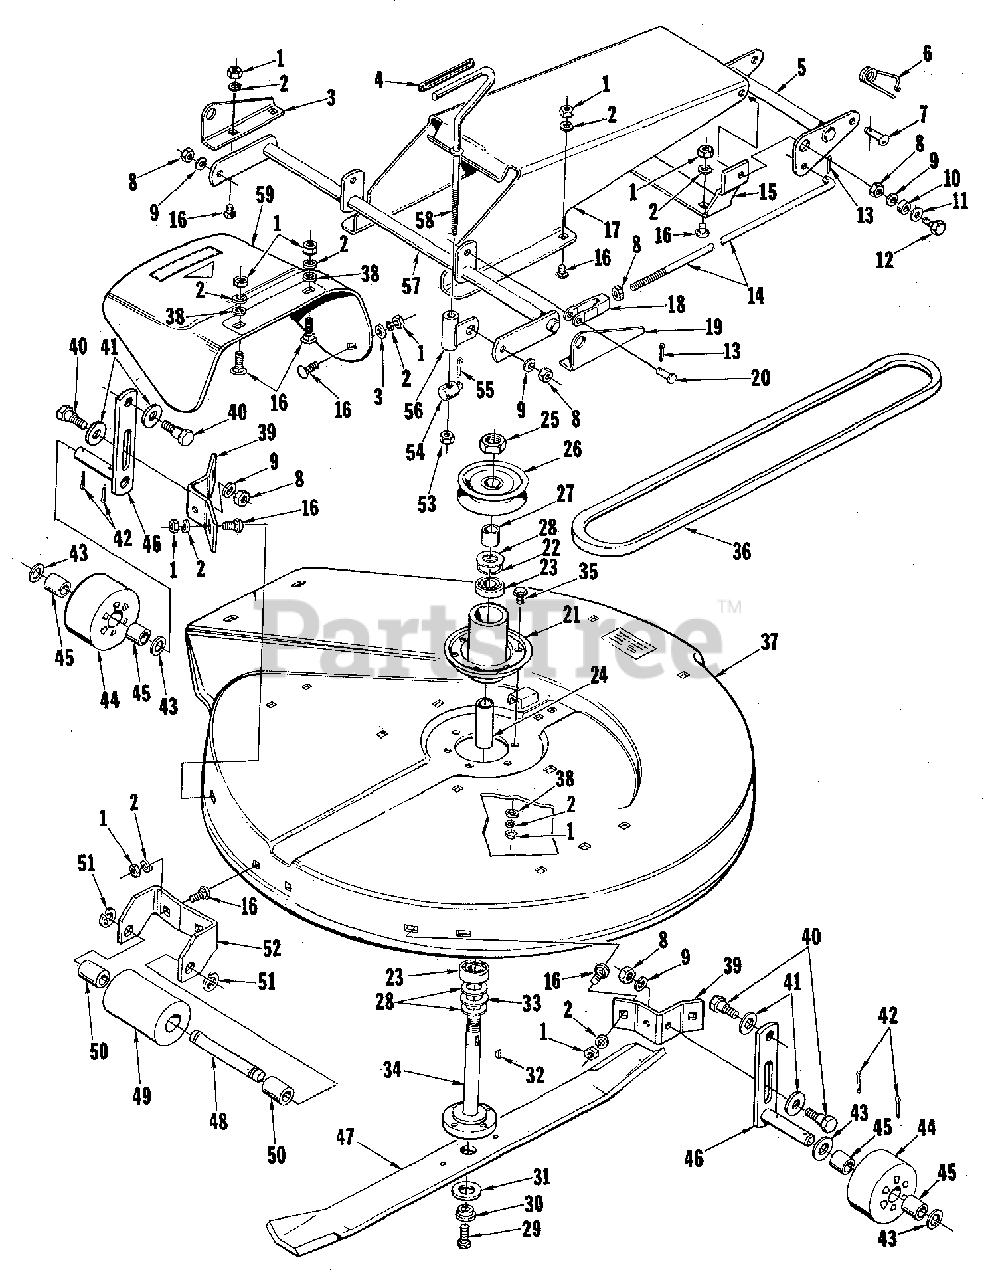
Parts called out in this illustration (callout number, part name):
1	NUT, Hex, 5/16-18
2	WASHER, Lock, 5/16
3	BRACKET, Pivot, L.H.
4	GRIP, Handle
6	PIN, Clip, Safety
8	NUT, Hex, 3/8-16
9	WASHER, Lock, 3/8
11	WASHER, Flat, 3/8
12	SCREW, Hex Cap, 3/8-16 x 1
13	PIN, Cotter, 3/32 x 3/4
14	ROD, Height Adjustable
16	BOLT, Carriage, 5/16-18 x 5/8
18	CLEVIS, Adjustable
19	BRACKET, Pivot, R.H.
21	ARBOR TUBE ASSEMBLY
22	RING, Backing
25	NUT, Lock, Jam, 3/4-16
28	WASHER, Special
29	SCREW, Hex, Cap, 1/2-20 x 1-1/2
30	WASHER, Shoulder
31	WASHER, Belleville
32	KEY, Woodruff, #61
33	WASHER, Special
34	ARBOR ASSEMBLY
35	SCREW, Hex Cap, 5/16-18 x 3/4
36	BELT, Mower Drive
37	HOUSING, 26" Mower
38	WASHER, Flat, 5/16
39	BRACKET, Roller Support
40	BOLT, Shoulder
41	WASHER, Flat, 7/16
42	PIN, Cotter, 3/16 x 1
43	WASHER, Flat
44	ROLLER ASSEMBLY, 3-1/2 O.D.
46	SUPPORT, Roller
47	BLADE, Mower, 26"
48	SHAFT, Center Roller
49	ROLLER ASSEMBLY
52	BRACKET, Center Roller
53	NUT, Hex, Lock, 3/8-16 x 1-1/4
55	PIN, Cotter, 3/32 x 5/8
